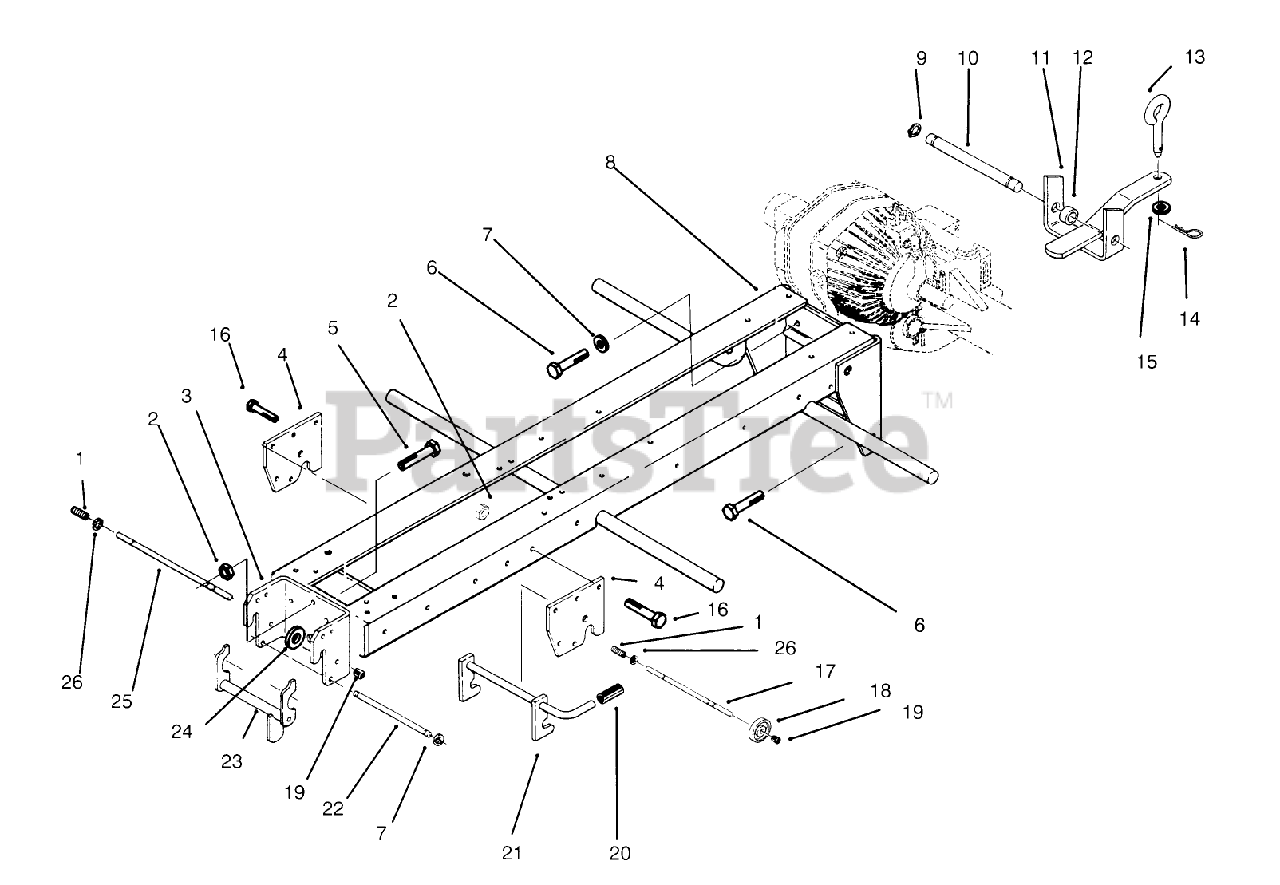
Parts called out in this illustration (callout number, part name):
1	SPRING
2	NUT-LOCK, NI
5	BOLT-CARR
6	SCREW-HH
7	WASHER-LOCK
9	E-RING
10	PIN-STATIONARY HITCH
13	PIN-TOOL
14	Hairpin Cotter
15	WASHER-FLAT
16	SCREW-HH
18	ROD-LOCK
19	CAP-ROD, PLUNGER
20	GRIP
21	MID HITCH ASM
22	ROD-LATCH PIVOT
23	LATCH
25	ROD-LOCK
26	RING-RETAINING
